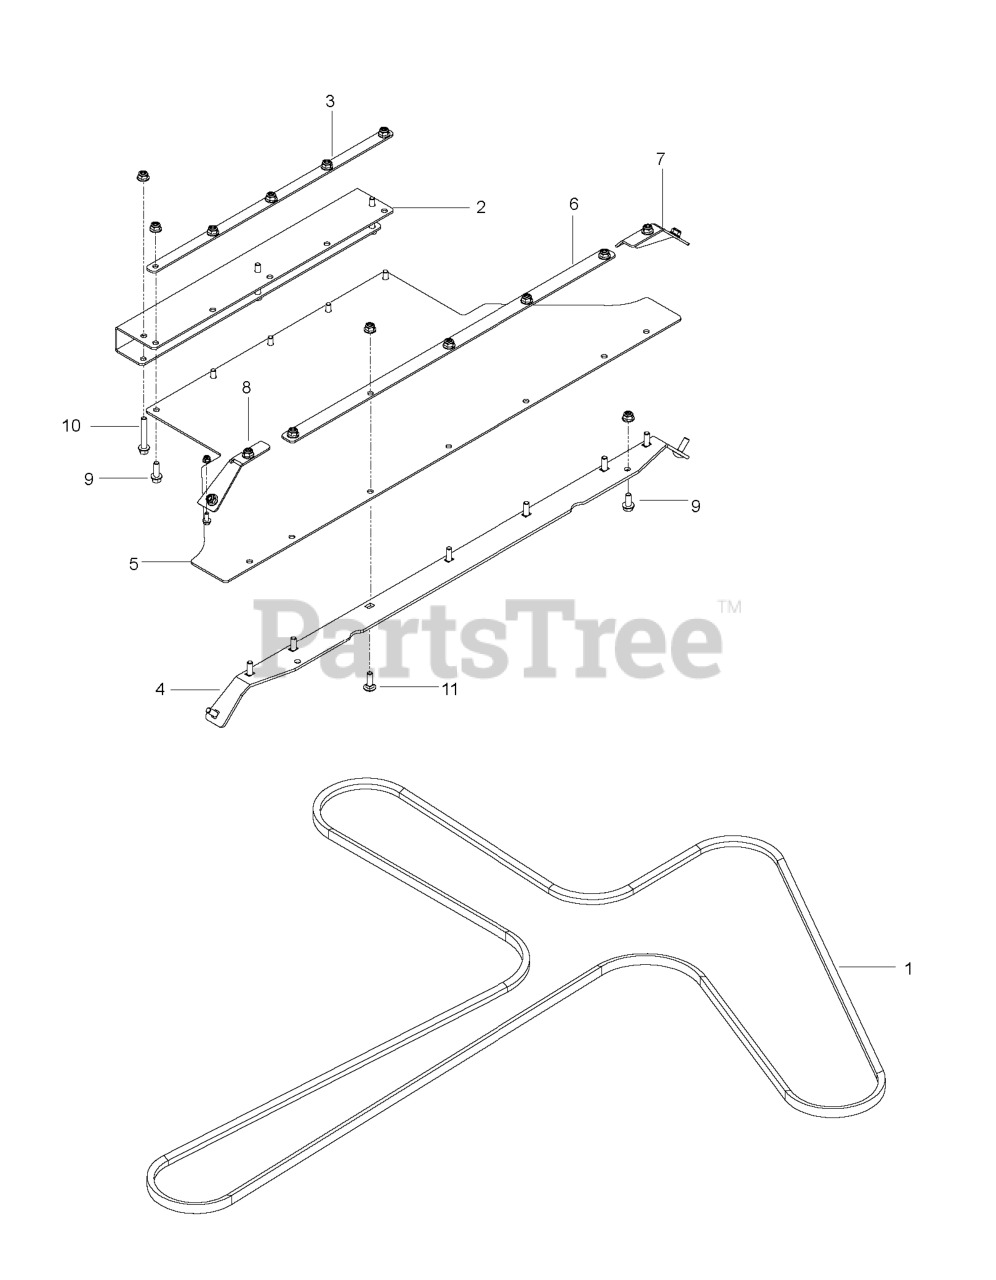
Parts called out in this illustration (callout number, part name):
1	BELT, "5V", 180"
2	CHANNEL, MTG BLACK
3	STRAP, SHORT BLACK
4	PLATE, MTG BLACK
5	GUARD, RUBBER 61C
6	STRAP, LONG BLACK
7	BRKT, L.H. CORNER BLK
8	BRKT, R.H. CORNER BLK
9	HHFS 5/16-18 X 3/4
10	HHFS 5/16-18 X 2.25 GD 5
11	RHSNB 5/16C X 1
